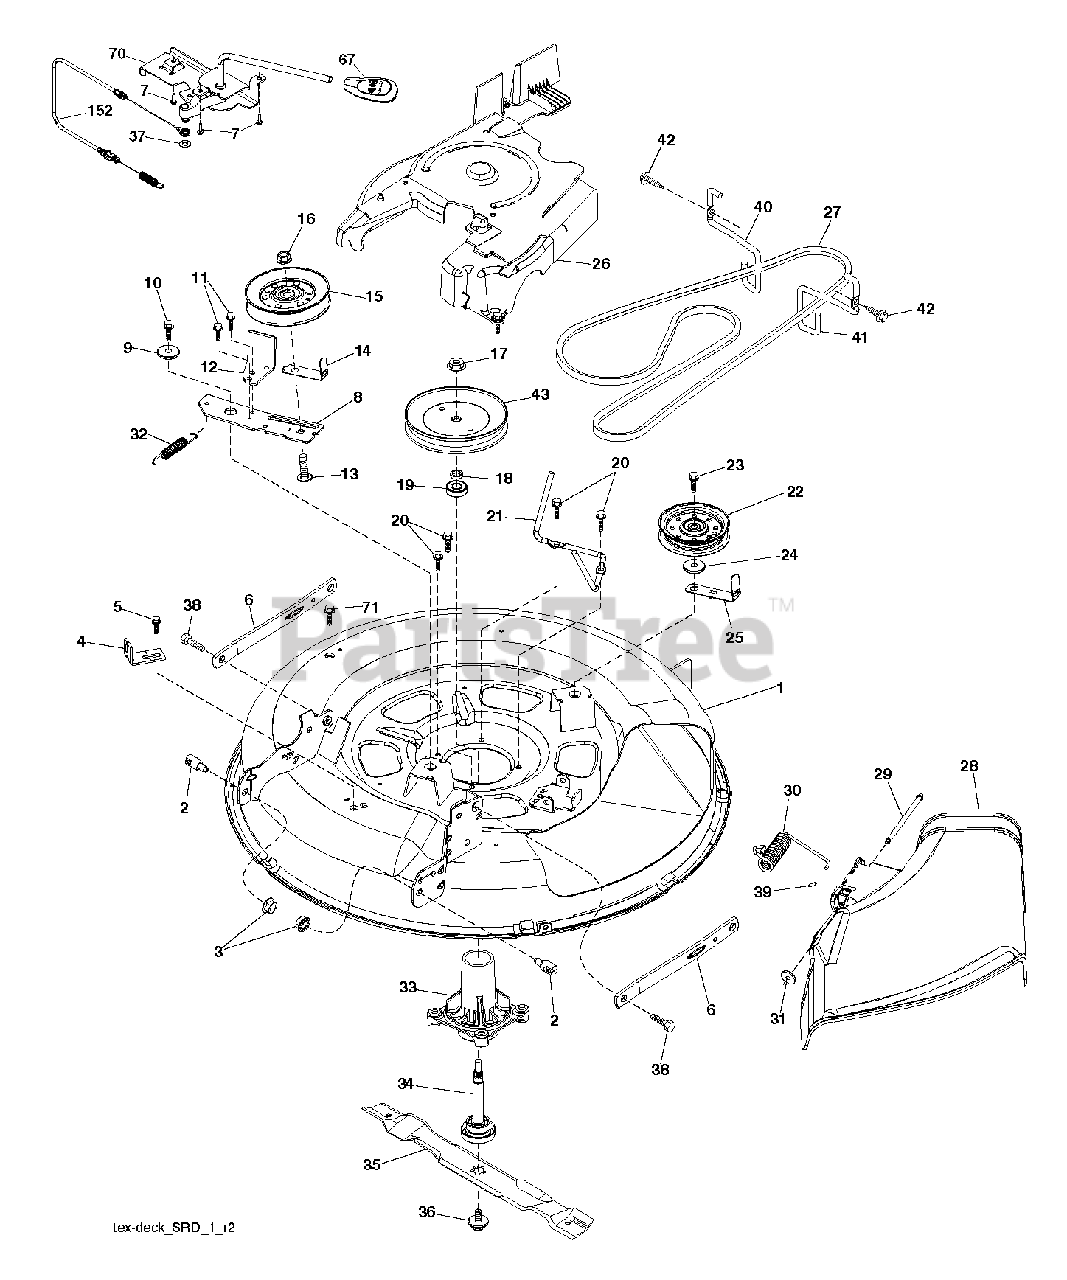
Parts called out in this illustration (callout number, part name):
1	DECK.WELDMENT.30"SRD.BLACK
2	STUD.FASTNER.W/ANTI-ROTATE
3	NUT LOCK HEX FLANGE 5/16-18
4	BRACKET.CLUTCH.CABLE
5	BOLT.5/16HEX.WHS.HD
6	ARMS.SUSP.MOWER.REAR.SRD
7	SCREW.#10 X 0.750.BOS (2 2)
8	ARM.IDLER.30"SRD
9	SPACER.RETAINER
10	SCREW 3/8-16X1
11	SCREW.1/4-20X5/8
12	ARM BRAKE MOWER RH
13	BOLT.3/8-16X1.50
15	PULLEY.IDLER.4.25
16	NUT LOCK FLG 3/8-16 UNC
17	NUT.FLANGE.LOCK.TOP
18	WASHER.SPACER.MANDREL
20	SCREW, WASHER HEAD
21	KEEPER.BELT.MANDREL.30"
22	PULLEY.IDLER.FLAT.46.PR.DR.
23	SCREW LT
25	KEEPER.BELT.30"SRD
27	V-BELT.DRIVE.MOWER.30"
28	SHIELD.DEFLECT.MWR.30S.BLACK
29	PIN.HINGE.30".SRD
30	SPRING.TORSION.DEFLECT
31	NUT PUSH M
32	SPRING RETURN
33	HOUSING.MANDREL.4PT.
34	SHAFT.ASM.MDRL.N/GREASE.38
35	BLADE.MOWER.BAGGING.30"
36	BOLT.WASHER.ASM.7/16-2
38	BOLT.SHOULDER
39	CAP-SLEEVE LT
40	KEEPER.BELT.ENGINE.LH.LT.SRD
41	KEEPER.BELT.ENGINE.RH.LT.SRD
42	SCREW, 3/8-16X3/4
43	PULLEY, MANDREL 6.5 PD
67	HANDLE.CLUTCH.CABLE.LT
70	CLUTCH.ASM.MANUAL.LT.TEX
71	SCREW 3/8-16X1/2
152	CABLE.CLUTCH.MANUAL.
